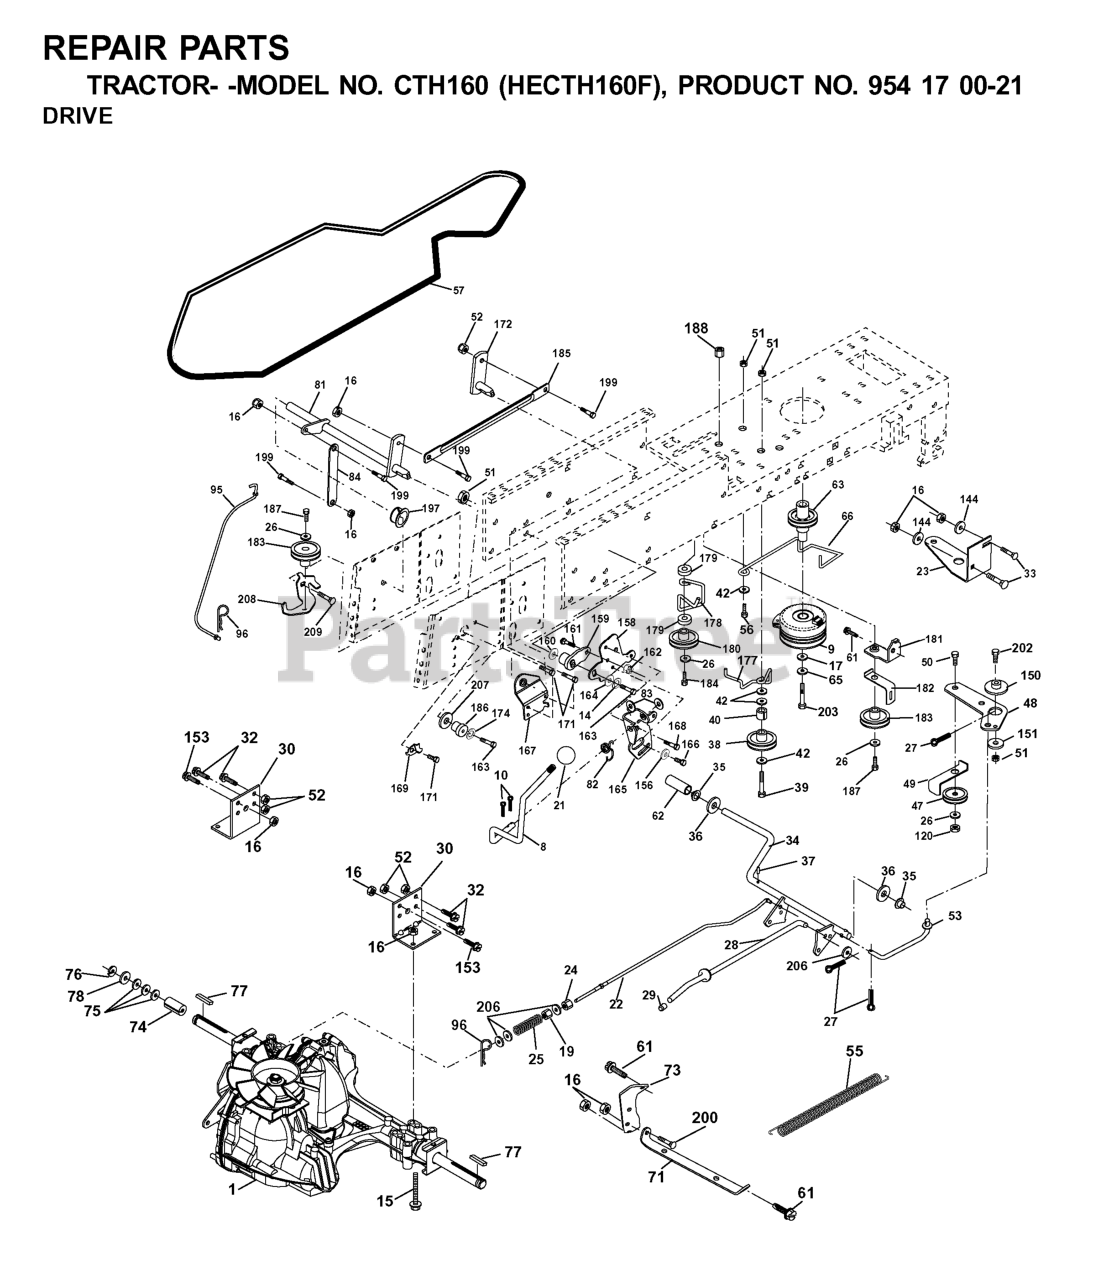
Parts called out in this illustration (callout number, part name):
8	ROD.SHIFT.FENDER.ADJ.LT.CRD
10	PIN COTTER
14	LOCKWASHER
15	BOLT HEX 5/16-18 GR 5
16	NUT.71038.31-18.HEX.NYLOCK
21	KNOB.DUCKHEAD.1/2
23	Bracket Clutch Noram
24	NUT
25	SPRING ROD LT
26	WASHER
27	COTTER PIN
28	ROD BRAKE PARK LT
29	PLUNGER CAP
30	BRKT, TRNSXLE MNT 20"
32	BOLT
33	RP BOLT 5/16-18 X3/4 ZN/YEL GR
35	BEARING.NYLON
37	DRIVE PIN
38	PULLEY.FLAT
42	WASHER
47	IDLER PULLEY
48	BELLCRANK, CLUTCH
49	RETAIN BELT
50	BOLT
52	LOCKNUT
53	LINK, CLUTCH LT
55	SPRING, RETURN LT
57	V-BELT 113"
61	SCREW 3/8-16X3/4
62	COVER, PEDAL (1 2)
63	PULLEY, CLUTCH ELECT EVX
65	LOCKWASHER
66	KEEPER BELT ENGINE
71	STRAP TORQUE LH HYDRO
73	STRAP TORQUE RH HYDRO
74	SPACER AXLE
77	SQUARE KEY
81	ASM.CROSS.SHAFT.REAR.CRD.0510
82	SPRING,TORSION
83	WASHER
84	LINK.PNT.TRANSAXLE.0510.CRD
95	LINK
96	RETAINER M
120	NUT LOCK FLG 3/8-16 UNC
144	Washer 11/32 x 5/8 x 16 Ga SD
150	BUSHING.BELLCRANK.GRD.DR
151	WASHER 12/32X2X10GA
153	BOLT RB
156	WASHER.SRRTD.5/16
158	BRACKET
159	HUB
160	Washer 29/32 x 1 - 1/4 x 16 Ga.
161	BOLT
162	NUT.CROWNLOCK.1/4
164	Washer 5/8 x .281 x 10 Ga.
165	RP BRACKET
167	BRACKET.SUPT.SHIFT.CRD
168	BOLT.SHOULDER.5/16-18X
169	PLATE.FASTENING.CROSS.SHAFT
172	LINK
174	LOCKWASHER
180	PULLEY.FLAT.IDLER
181	BRKT.IDLER.GRD.DR.CRD
182	KEEPER BELT
183	PULLEY.V-IDLER
184	SCREW.HXWSH.3/8
185	LINK
186	HUB.TAPERED.ROUND.CRD
187	SCREW.3/8-16
188	SNAP BUSHING T
197	NYLINER SNAP 5/8" ID
199	BOLT SHOULDER 5/16-18 UNC
202	BOLT.3/8-16X1.50
203	BOLT.HEX.7/16-20 X 5
206	WASHER
207	WASHER NYL
